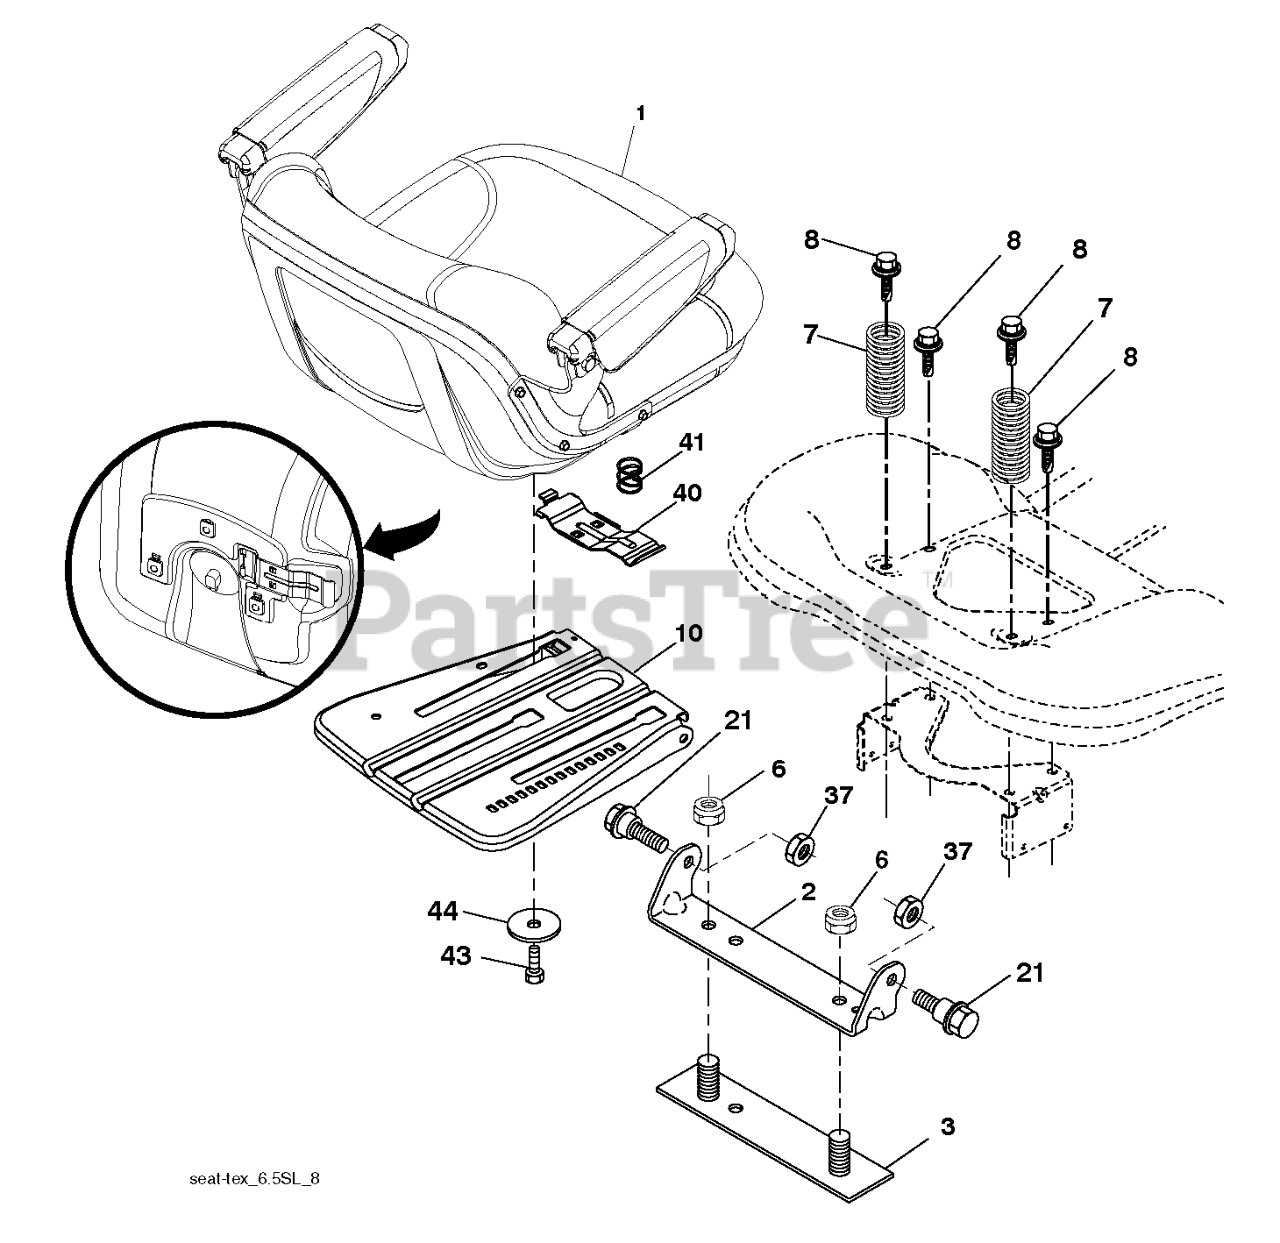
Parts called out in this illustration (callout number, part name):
1	SEAT.TH154.GREY.HUS.ARMREST
2	BRKT.PIVOT.FENDER
3	STRAP
6	NUT
7	SPRING.COMPRESSION.SEAT.BLACK
8	BOLT.5/16-18UNCX3/4 W/SEMS.BLK
10	PAN.ASM.SEAT.3PT
21	BOLT.5/16-18X5/8.SHOULDER
37	NUT.71038.31-18.HEX.NYLOCK
40	HANDLE.SLIDE.SEAT.TEX.GREY
41	SPRING.LATCH.SEAT.TEX
44	WASHER 13/32 X 2-3/8 X 12GA
